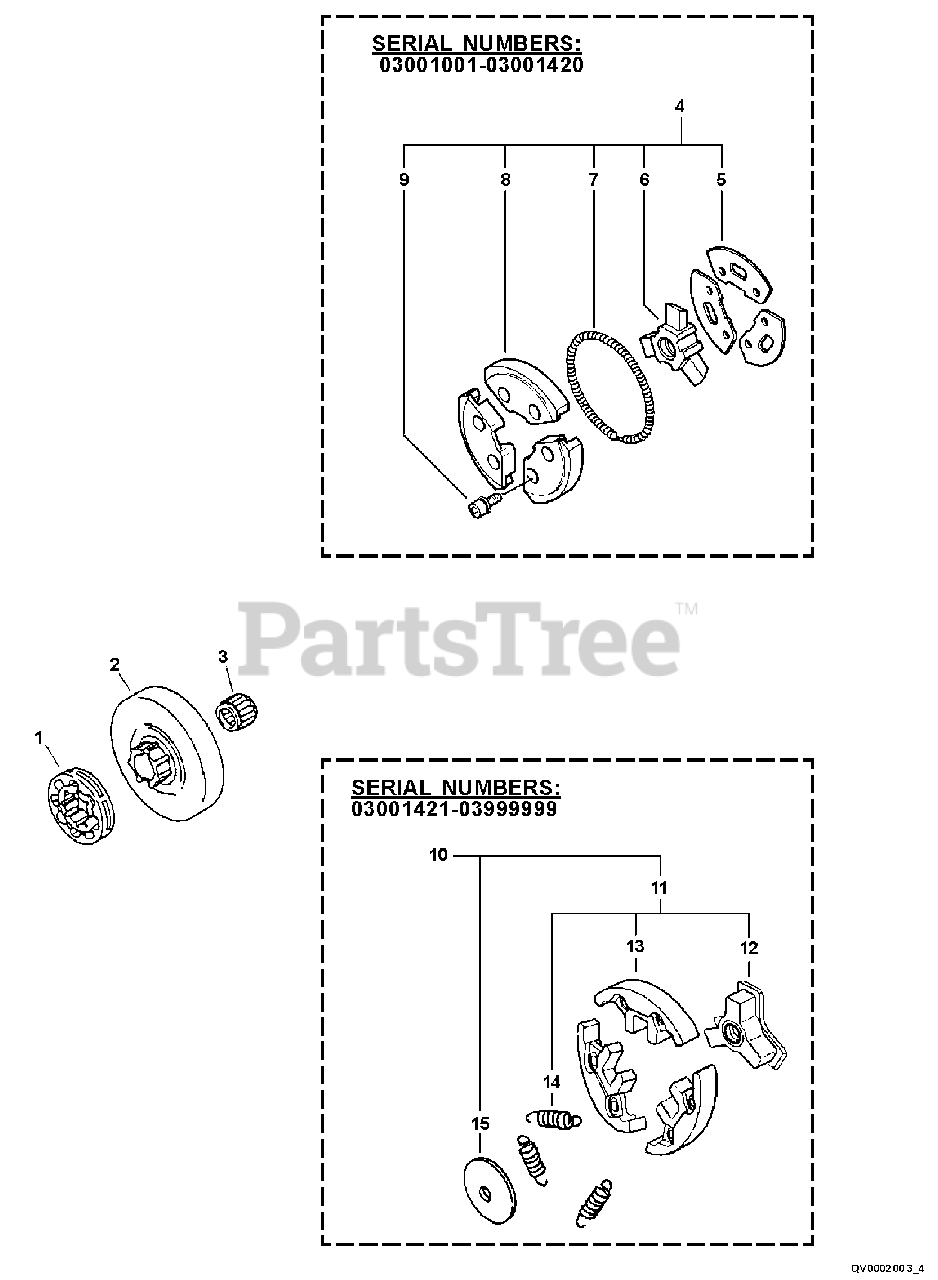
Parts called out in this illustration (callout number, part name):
1	SPROCKET, RIM
2	DRUM, CLUTCH
3	BEARING, NEEDLE
4	CLUTCH ASSY
5	PLATE, CLUTCH
6	HUB, CLUTCH
7	SPRING, CLUTCH
8	CLUTCH SHOE SET
9	SCREW - 4X6
10	CLUTCH ASSY
11	CLUTCH ASSY
12	HUB, CLUTCH
13	CLUTCH SHOE SET
14	SPRING, CLUTCH
15	PLATE, CLUTCH
